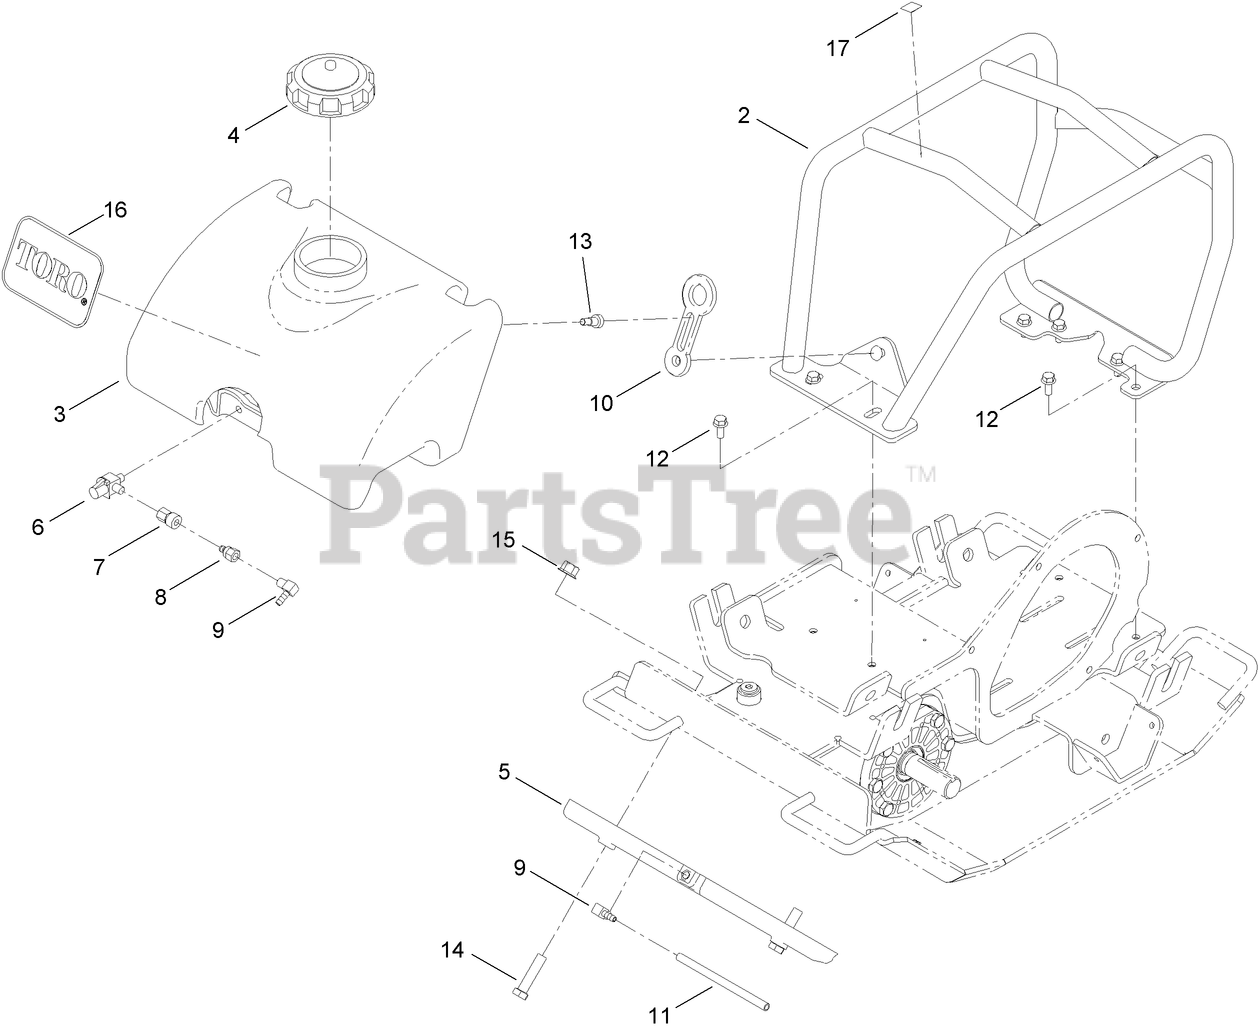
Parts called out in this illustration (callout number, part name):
2	CAGE-ROLL
3	TANK-WATER
4	CAP-PLASTIC
5	SPRINKLER
6	VALVE-BALL
7	FITTING-QUICK, FEMALE
8	FITTING-QUICK, FEMALE, NIPPLE
9	FITTING-HYD, 90 DEG
10	LATCH-RUBBER
11	HOSE-WATER
12	SCREW-HHF
13	SCREW-HSBH
14	SCREW-HH
15	NUT-LOCK, HHF
16	DECAL
17	DECAL-POINT, LIFT
